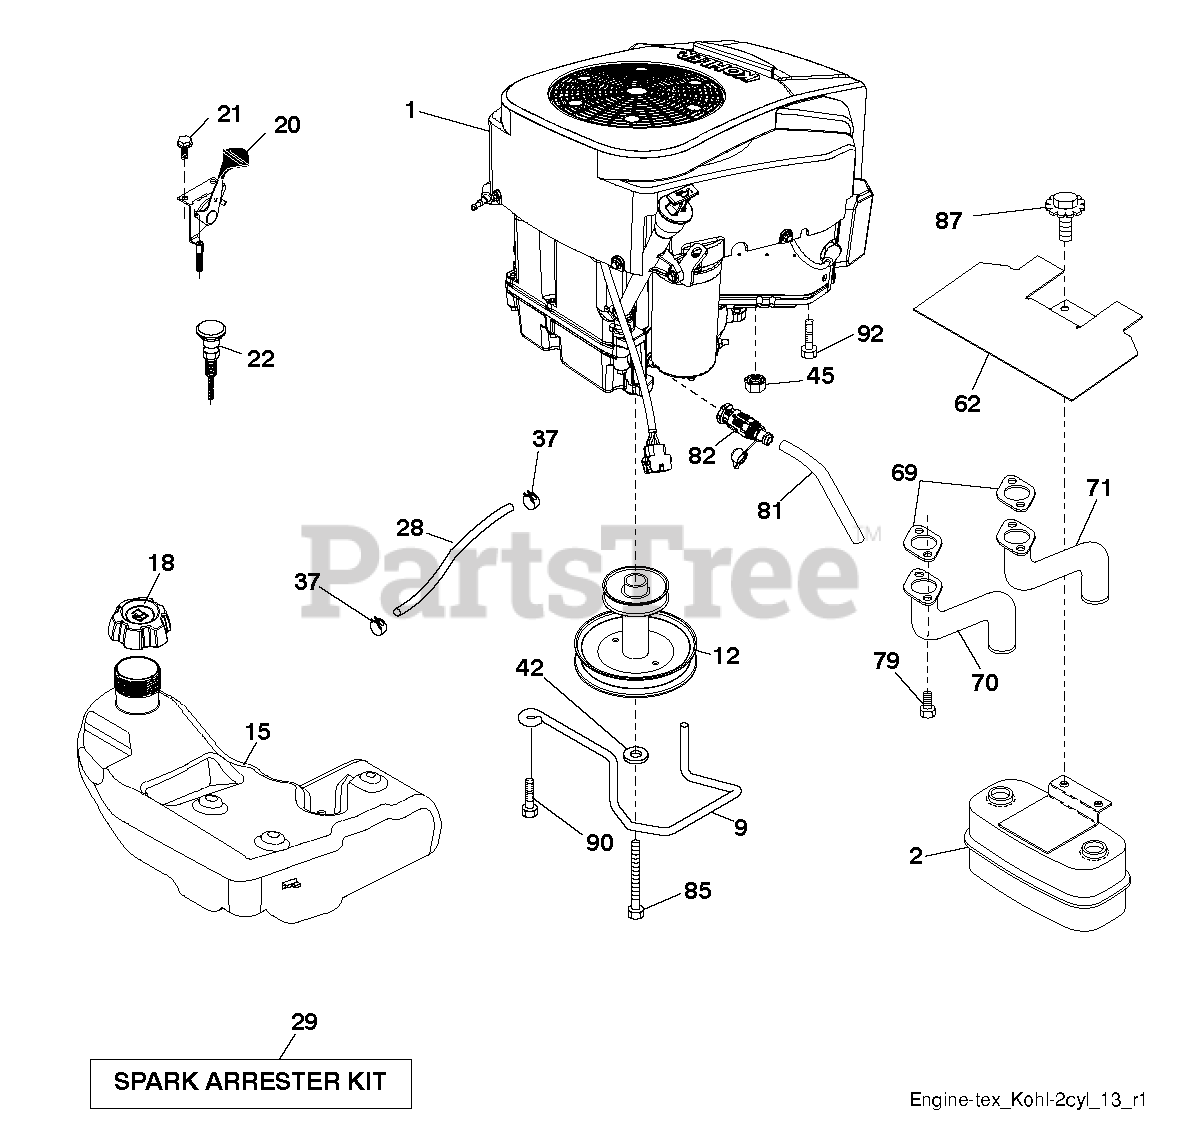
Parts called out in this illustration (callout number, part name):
2	MUFFLER.ASM.TWN.EXTNDED.DFLCTR
9	KEEPER.BELT.ENGINE.4.2
12	PULLY ENGINE
15	TANK.ASSY.3.GAL.EPA
18	CAP.ASM.FL.RITCH.3"E10.SYM.498
20	THROTTLE CONTROL
21	SCREW.#10 X 0.750.BOS
22	CONTROL.CHOKE.ERGO.PUSH-IN.BLA
28	LINE.FUEL.20
29	KIT.SPARK ARRESTOR 794945 B&S
37	HOSE CLAMP
42	LOCKWASHER
45	NUT
62	SHIELD.HEAT.MUFFLER
69	GASKET.EXHAUST.KOHL.CV18-CV26
70	RP.PIPE-EXHAUST LH
71	RP.PIPE-EXHAUST RH
79	SCREW.SOCKET HD.5/16-1
81	TUBE, DRAIN OIL ASM.
82	VALUE.OIL.DRAIN
85	BOLT HEX 7/16-20X4-1/4"
87	Bolt, 5/16-18 X 1-3/4
90	SCREW 3/8-16X1
92	SCREW 3/8-16X1
